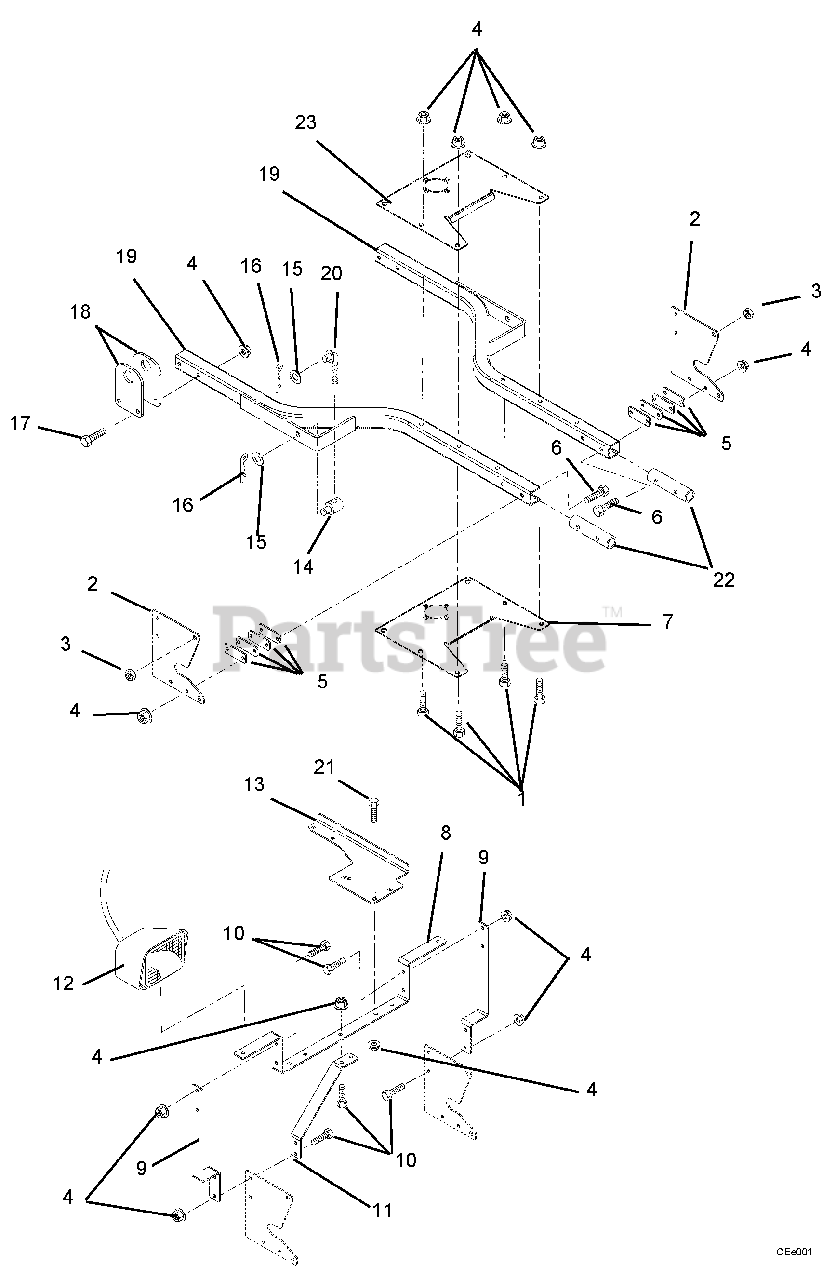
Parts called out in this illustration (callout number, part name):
1	Hex Bolt, .38-16 x 2.50 Grade 5
2	Plate, Sno-ThroO Mount
3	Nut, Locking, Center .50-13
4	Nut, Locking, Top, Flange .38-16
5	Plate, Shim
6	Bolt, Hex .38-16 x 3.00 Grade 5
7	Plate, Subframe
8	Light-Bar, Snow Throw
9	Support, Light-Bar, Snow Throw
10	Bolt, Hex .38-16 x 1.00 Grade 5
11	Gusset, Light-Bar
12	Headlight
13	Bracket, Deflector Control
14	Trunnion
15	Flat Steel Washer, .531 x 1.250 x .100
16	External Hair Pin - #16 Black Zinc
17	Hex Bolt, .38-16 x 2.5 Grade 5
18	Pivot Bracket
19	Weldment, Sub-Frame Tube
20	Lift Link
21	Bolt, Round Head Square Neck .38-16 x 1.00 Grade 5
22	Tube, Anti-Crush
23	Plate, Subframe Top
